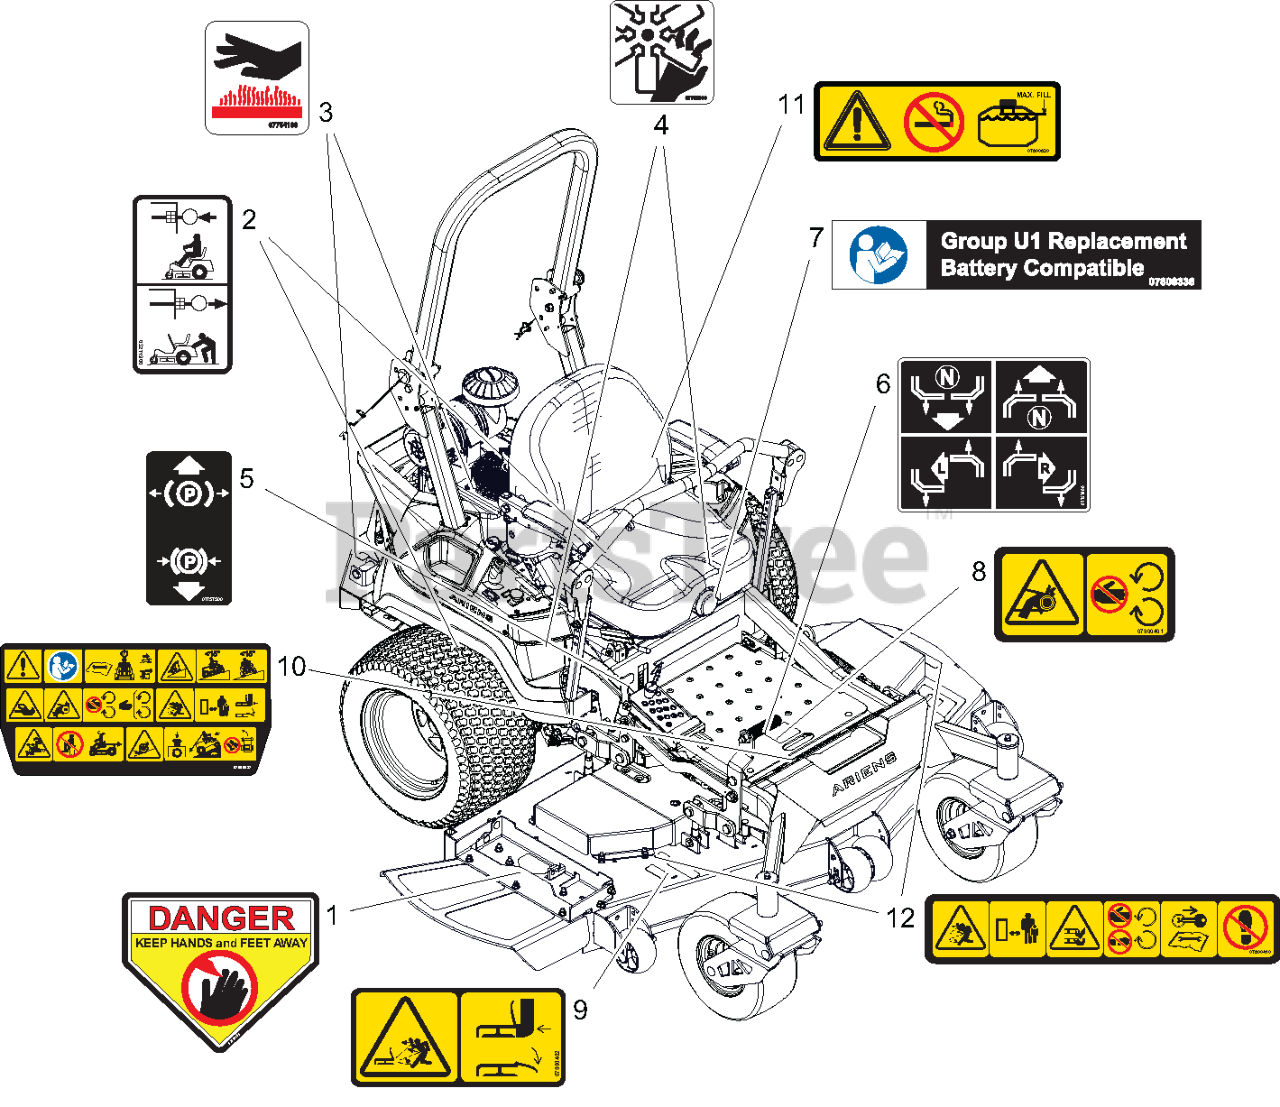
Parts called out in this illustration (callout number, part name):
1	DECAL, DANGER
2	DECAL, TRANSMISSION DISCONNECT
3	DECAL, HOT SURFACE
4	DECAL, DANGER FAN
5	DECAL, PARKING BRAKE LEVER
6	DECAL, INSTRUCTIONAL-STEERING
7	DECAL, U1 BATTERY REPLACEMENT
8	DECAL, SAFETY - GUARDING
9	DECAL, SAFETY - DECK GUARDING
10	DECAL, MAIN SAFETY
11	DECAL, FUEL WARNING
12	DECAL, DECK SAFETY
